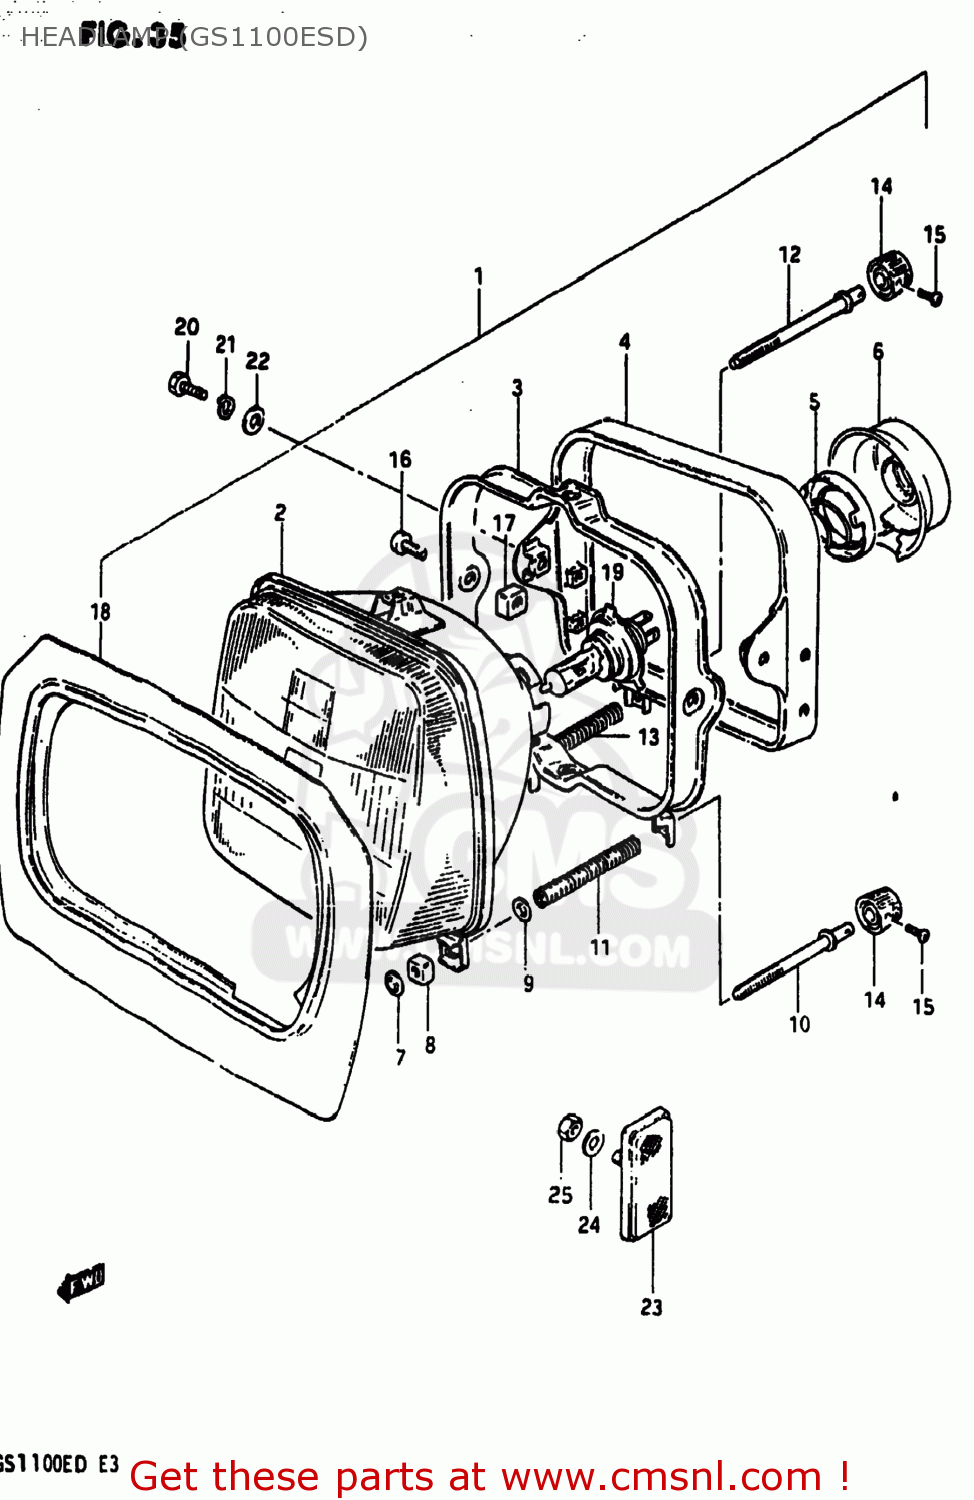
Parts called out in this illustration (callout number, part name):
1	LAMP ASSEMBLY,HEAD
2	LAMP UNIT
3	RING,MOUNTING
4	HOUSING,LAMP UNIT
5	HOLDER
6	COVER,HEADLAMP SOCKET
7	NUT,HEADLAMP ADJUSTER
8	NUT,HEADLAMP ADJUSTER
9	WASHER
10	SCREW,HEADLAMP ADJUST
11	SPRING
12	SCREW,ADJUSTING
13	SPRING
14	KNOB,ADJUSTER
15	SCREW
16	SCREW
17	NUT
18	SHADE
19	BULB(12V60/55W,H4)
20	BOLT
21	LOCK WASHER
22	WASHER
23	REFLEX REFLECTOR ASSEMBLY
24	WASHER
25	NUT
